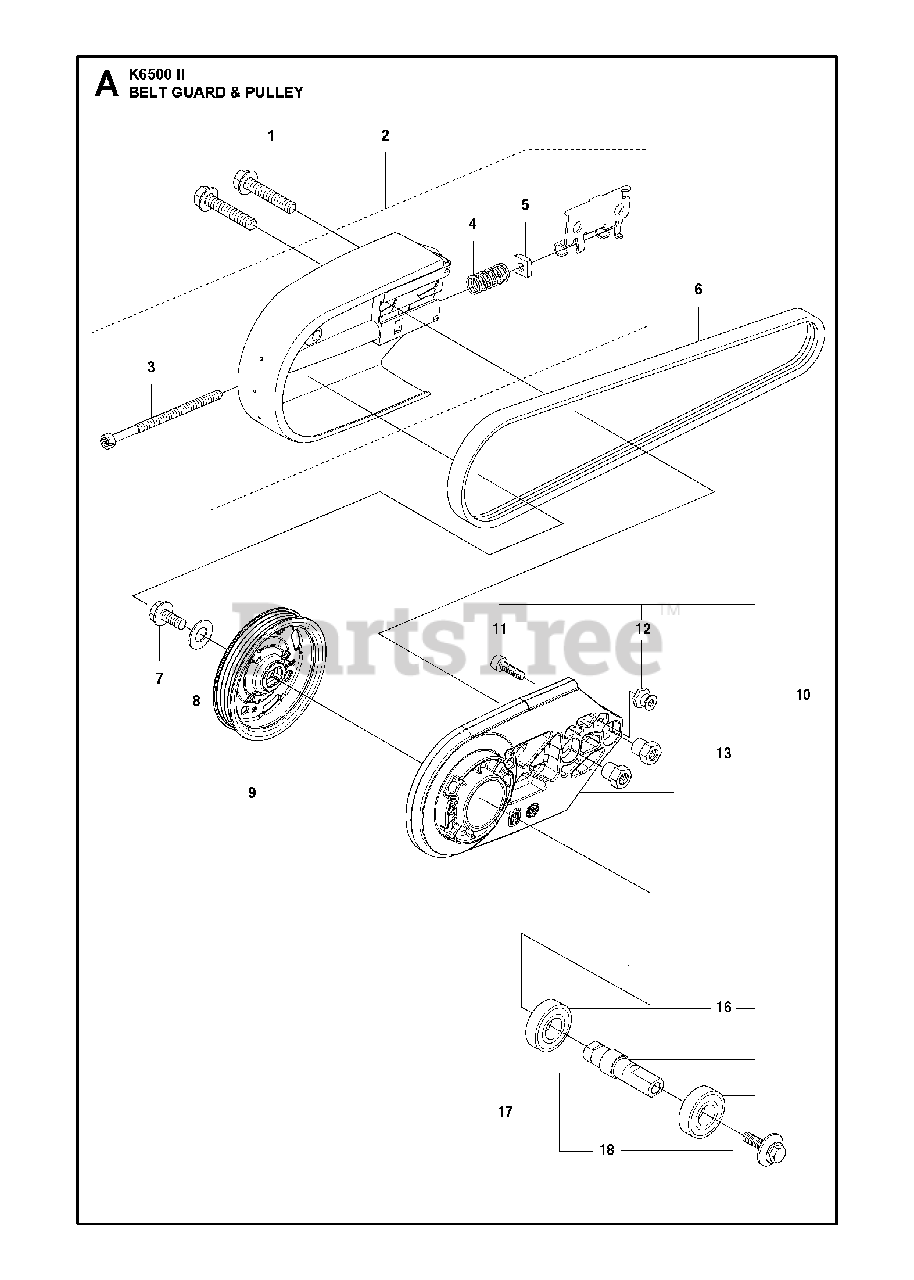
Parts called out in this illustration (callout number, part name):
3	SCREW CITXSCM
4	COMPRESSION SPRING
11	SCREW ITXSCM
16	BALL BEARING
